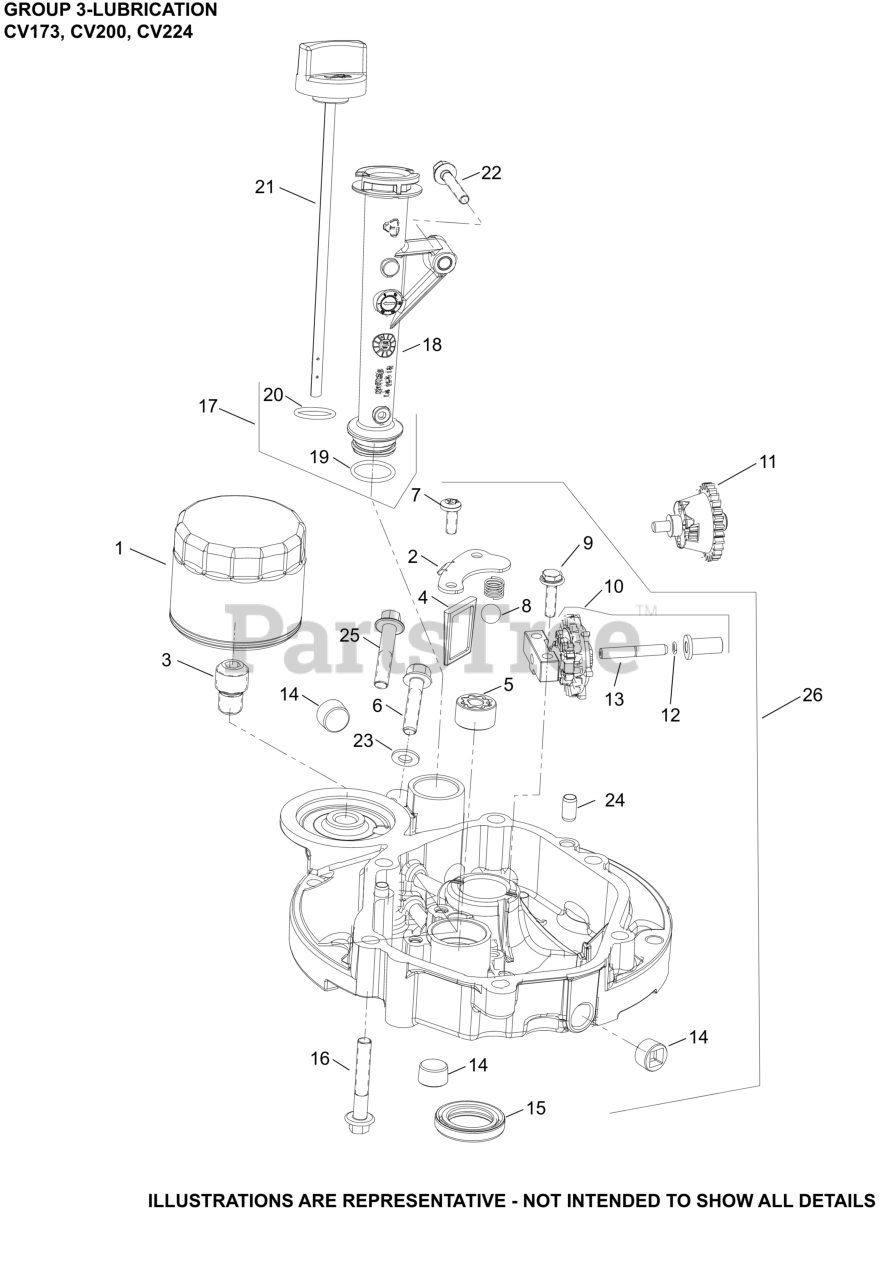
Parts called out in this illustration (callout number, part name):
1	FILTER, OIL
2	COVER, OIL PUMP SCREEN
3	NIPPLE, OIL FILTER
4	SCREEN, OIL
5	PUMP ASSEMBLY, OIL (GE-ROTOR)
7	SCREW, M6 X 16
8	BALL, STEEL COMPOSITE
9	SCREW, M6 X 22
10	GOVERNOR GEAR, ASSEMBLY
12	CLIP, GOVERNOR GEAR-DISCONTINUED
13	SHAFT, GOVERNOR GEAR-DISCONTINUED
14	PLUG, PIPE (W/SEALANT)
16	SCREW, HEX FLANGE (M8)-USE 25 086 456-S
17	KIT, DIPSTICK AND TUBE-(#1412320S)
18	TUBE ASSEMBLY, OIL FILL
19	O-RING, OIL FILL TUBE
20	O-RING (CAP)
21	CAP, DIPSTICK ASSEMBLY
22	SCREW, HEX FLANGE (M6)-(#25086435S)
23	WASHER, CLEAN OIL SCREW
24	PIN, DOWEL (8MM)
25	SCREW, CLOSURE PLATE
26	PAN, OIL ASSEMBLY (KIT)
